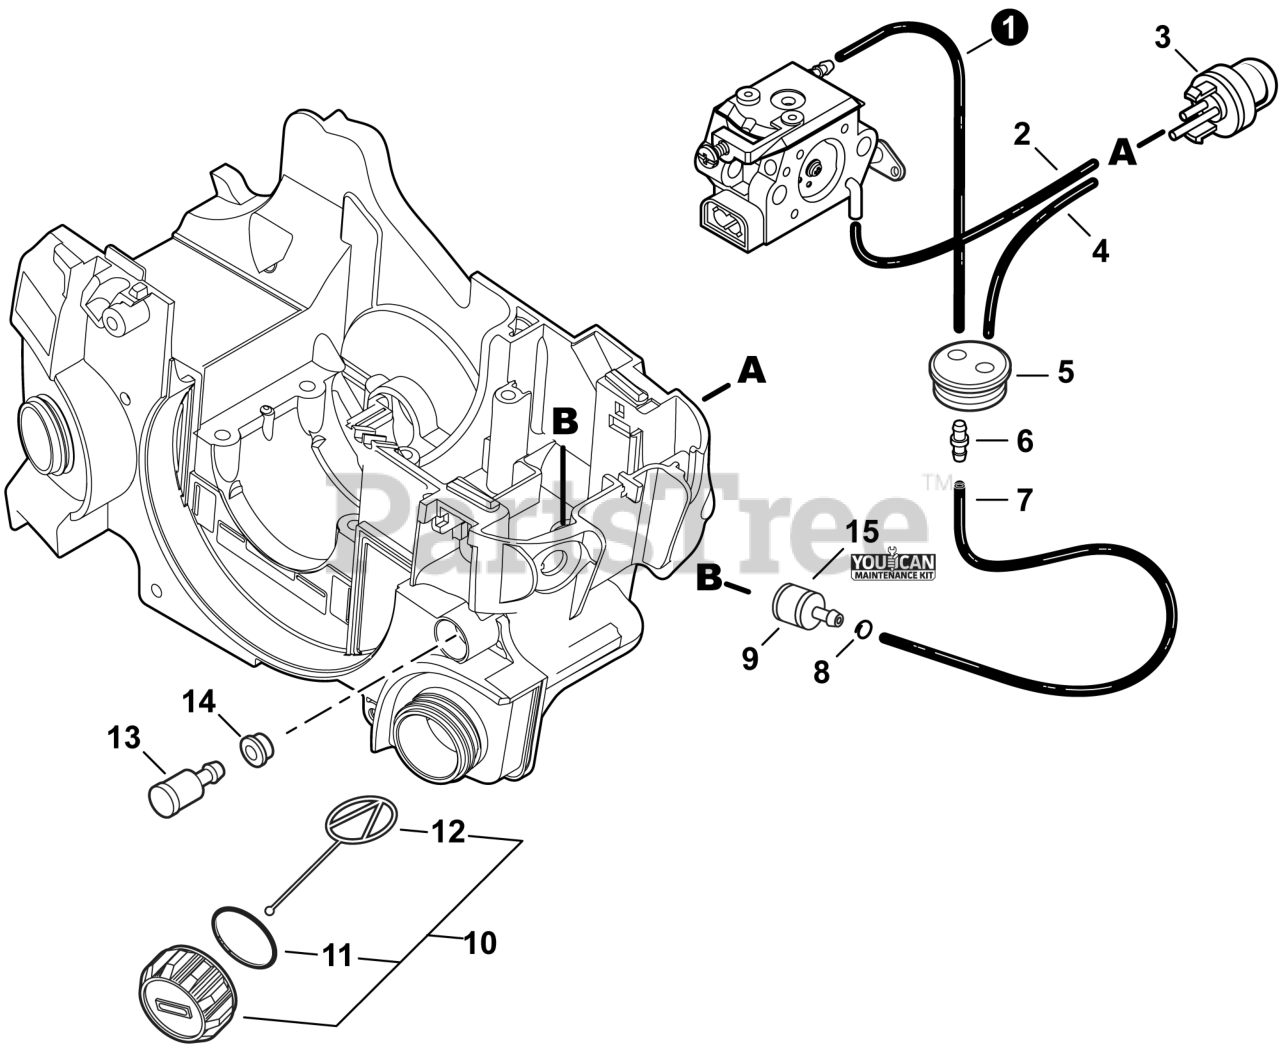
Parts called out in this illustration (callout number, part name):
1	PIPE, FUEL 3×5×85 BLACK
2	PIPE 2.4×5×105 BLACK
3	BULB, PURGE
4	PIPE, FUEL 2.4×5×80 BLACK
5	GROMMET, FUEL
6	CONNECTOR, PIPE
7	PIPE, FUEL 3×5×144 BLACK
8	CLIP Ø6
9	FILTER, FUEL
10	CAP ASSY, FUEL
11	O-RING 22
12	FUEL CAP CONNECTOR (L=60MM)
13	VENT ASSY
14	GROMMET, FUEL
15	TUNE-UP KIT - YOUCANT
